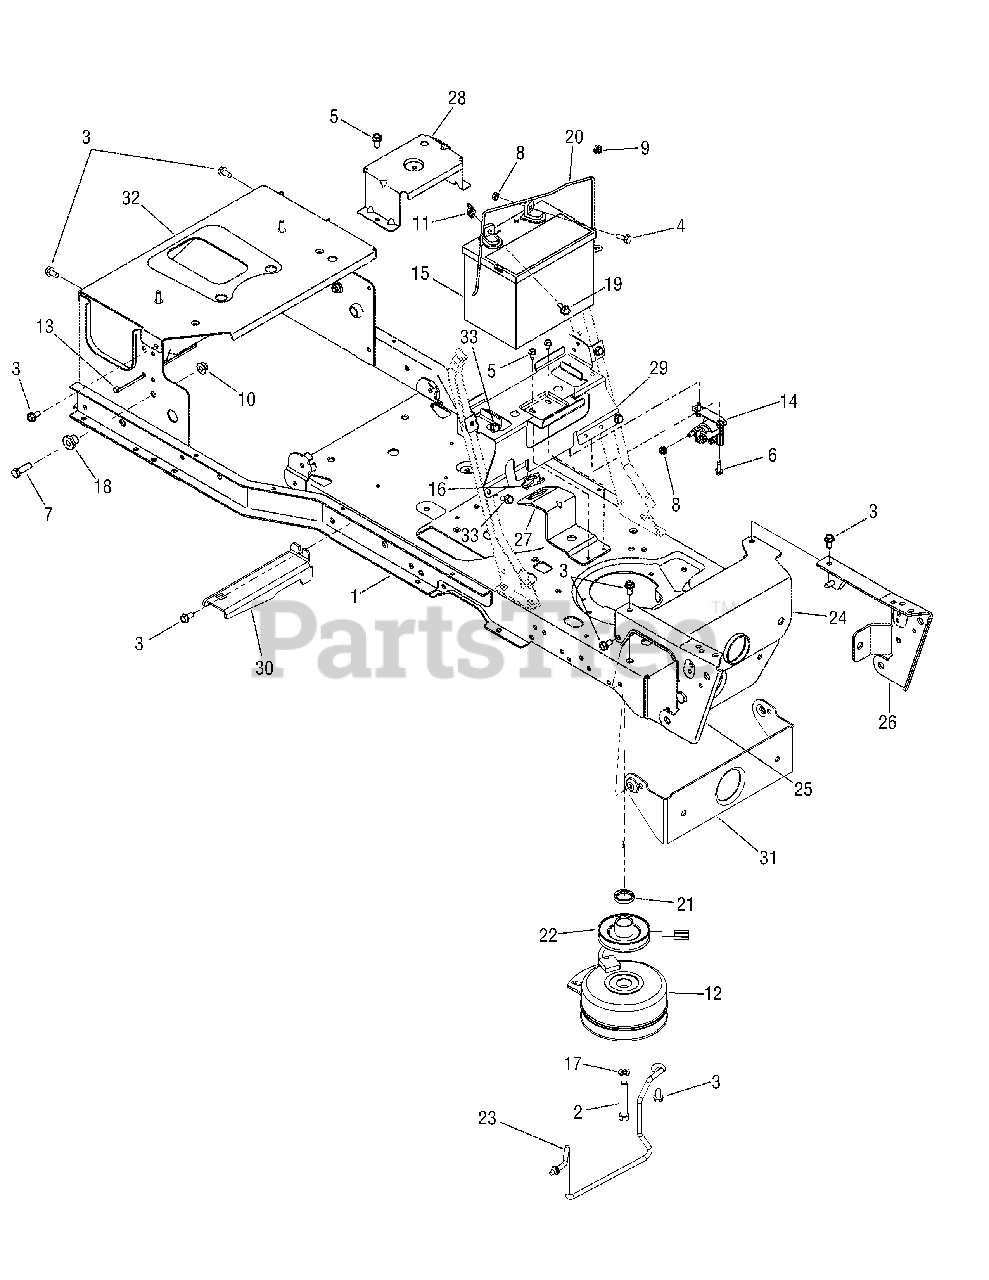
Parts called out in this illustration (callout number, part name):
3	Screw, Hex Wash. Hd. Tapp, 5/16-18 x .75
4	Screw, Hex Flange Hd. , 1/4-20 x .75 Gr5
5	Screw, Hex Wash. Hd. Tapp, 1/4-20 x .5
6	Screw, Hex Wash. Hd. Tapp, 1/4-20 x .75
7	Screw, Hex Cap, 3/8-16 x 1.25 Gr5
8	Nut, Hex Sems, 1/4-20
9	Nut, Hex Flange Insert Lock, 1/4-20 GrF
10	Nut, Hex Flange Insert Lock, 3/8-16 GrF
11	Nut, Wing, 1/4-20
12	Clutch, Electric PTO
13	Cable Tie
14	Solenoid, Start
15	Battery - Dry
16	Bushing, Steering Shaft
17	Washer, Lock, 7/16
18	Spacer, Shoulder, .38 x 1.0 x .7
19	Screw, Shoulder, .25 x .15:1/4-20
21	Spacer, 1.37 x 1.00 x .25
22	Pulley, Engine
23	Rod, Belt Keeper
